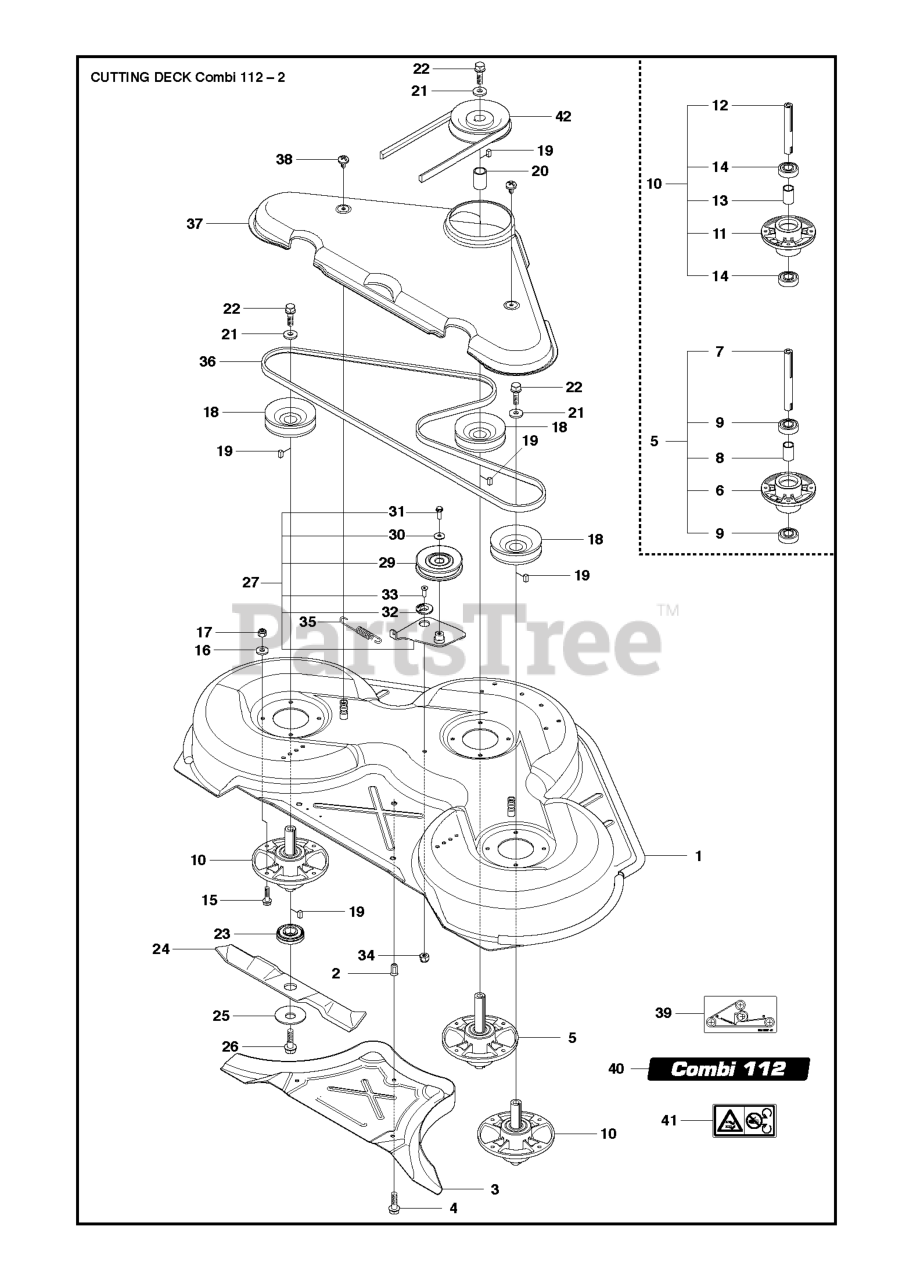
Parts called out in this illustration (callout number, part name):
1	CUTTING DECK
5	BLADE HOUSING ASSY
6	BEARING HOUSING
8	SPACING SLEEVE
10	BLADE HOUSING ASSY
11	BEARING HOUSING
13	SPACING SLEEVE
16	WASHER BRB 8.4X17
17	LOCKNUT M8
27	BELT TENSIONER ASSY KIT
32	WASHER SHOULDER ASSY
34	LOCKNUT M8
36	BELT
37	BELT COVER
